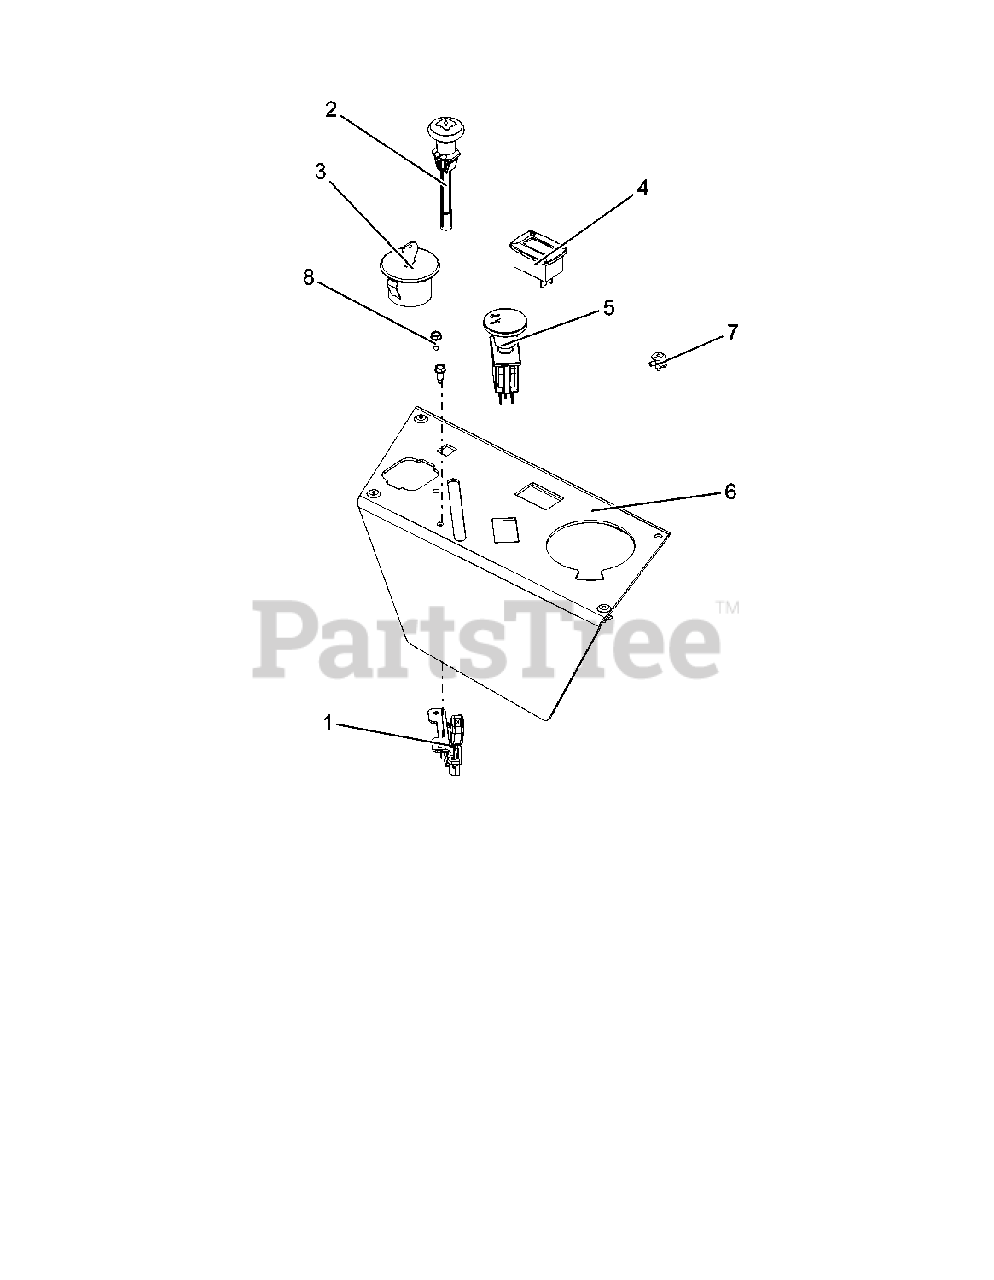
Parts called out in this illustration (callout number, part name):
1	CABLE - THROTTLE CONTROL
1	KEYSWITCH-IGNITION 3 POS
1	KEYSWITCH-IGNITION 4 POS
2	CABLE - CHOKE, SNAP-IN
4	METER, HOUR W/MAINTENANCE
5	SWITCH, CLUTCH (YELLOW)
6	PANEL, CONTROL
7	RIVET, PLASTIC .195 DIA.
8	@SCR-TAP 10-24X.50 HWH TR YWZC
